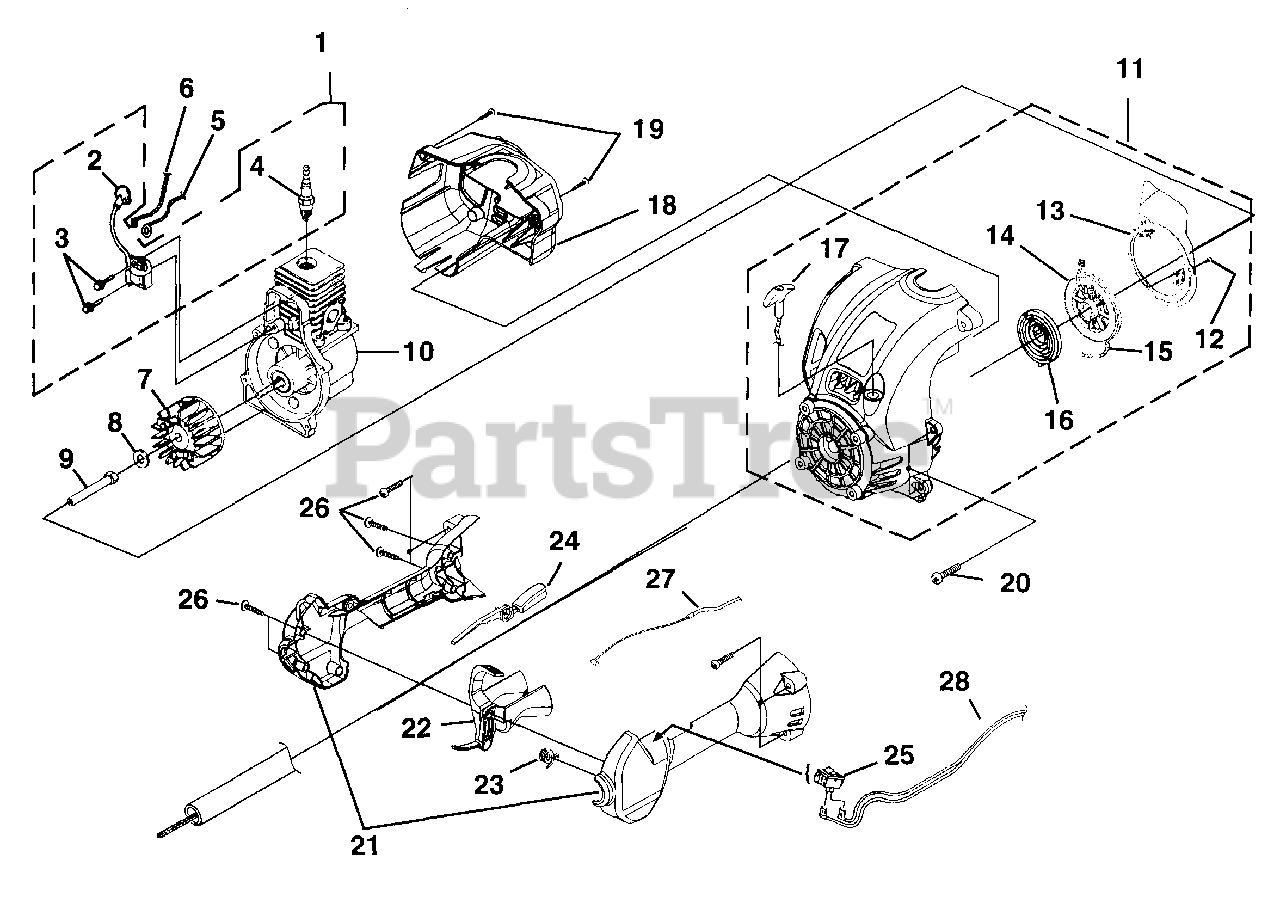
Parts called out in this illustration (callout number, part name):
1	IGNITION KIT
2	TERMINAL & COVER
3	SCREW-Taptite (8-32 X 1")
4	SPARK PLUG (RDJ-7Y)
5	LEAD-Electrical
6	LEAD-Electrical
7	ROTOR KIT
8	WASHER-Flat
9	CONNECTOR AND DRUM
10	SHORT BLOCK
11	COMPLETE STARTER ASSEMBLY
12	SCREW-Thread Form (8-16 X 1/2")
13	BAFFLE-Air
14	PULLEY-Starter
15	ROPE-Starter (42")
16	SPRING & CONTAINER
17	GRIP-Starter (Yellow)
18	HOUSING-Rear Kit
19	SCREW-Plastite (10-14 X 3/4")
20	SCREW-Taptite (10-24 X 3/4")
21	CONTROL HANDLE ASSY.
22	TRIGGER-Throttle
23	SPRING
24	THROTTLE INTERLOCK
25	SWITCH
26	SCREW-Taptite (10-14 X 1")
27	CABLE-Throttle
28	LEAD-Electrical
